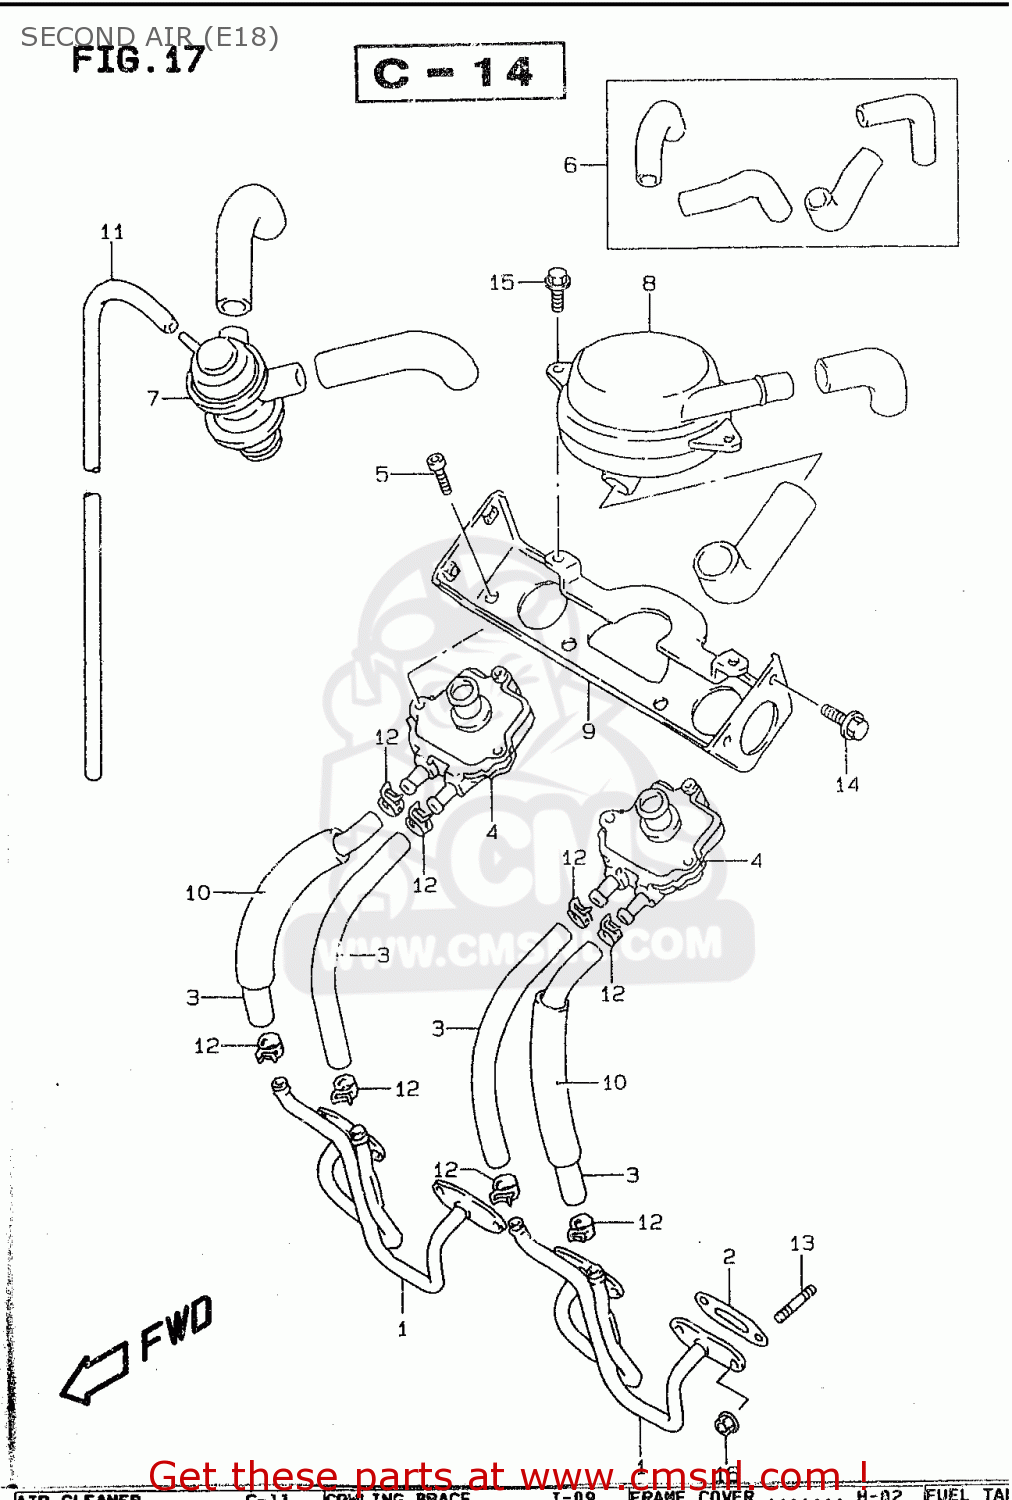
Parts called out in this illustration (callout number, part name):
1	PIPE,2ND AIR,L
2	GASKET,SECOND AIR PIPE (NAS)
3	HOSE,SECOND AIR REED VALVE
4	VALVE ASSY,2ND AIR REED
5	BOLT
6	HOSE SET,SECOND AIR
7	VALVE ASSEMBLY,SECOND AIR SWITCH
8	CLEANER ASSEMBLY,SECOND AIR
9	BRACKET,SECOND AIR
10	PROTECTOR,REED VALVE
11	HOSE(4.5X8.5X600)
12	CLIP
13	STUD BOLT
14	BOLT,STRANGER
15	BOLT
16	NUT
